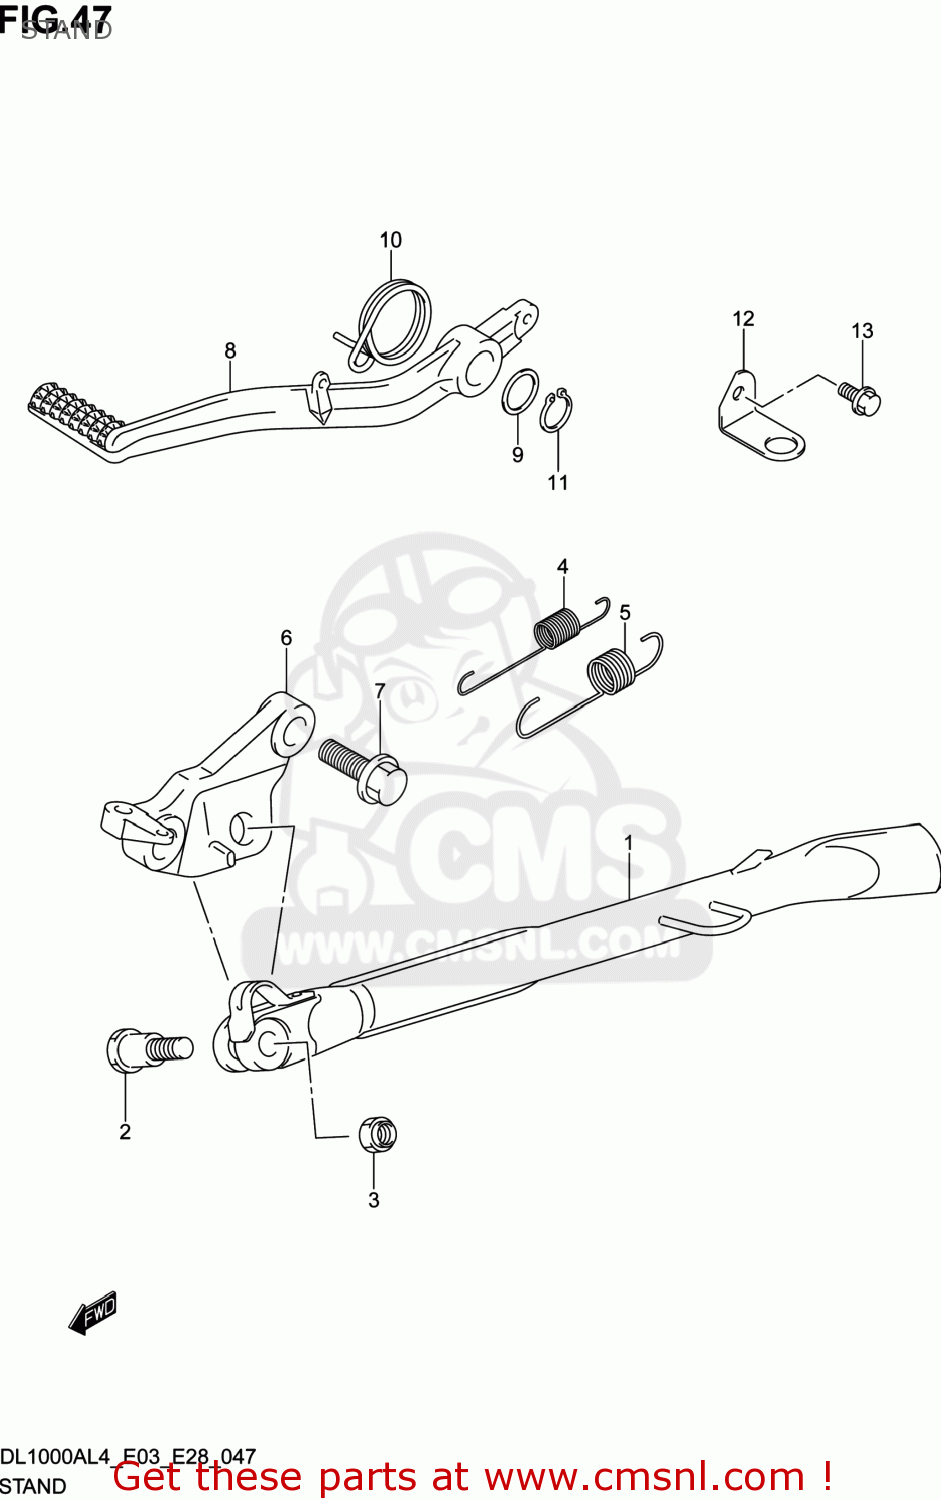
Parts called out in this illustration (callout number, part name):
1	STAND COMP,PROP
2	BOLT(10X37.5)
3	NUT,PROP STAND
4	SPRING
5	SPRING
6	BRACKET,PROP STAND
7	BOLT
8	PEDAL,BRAKE
9	WASHER(18X24X1)
10	SPRING
11	CIRCLIP
12	BRACKET,STOP LAMP SWITCH
13	BOLT
